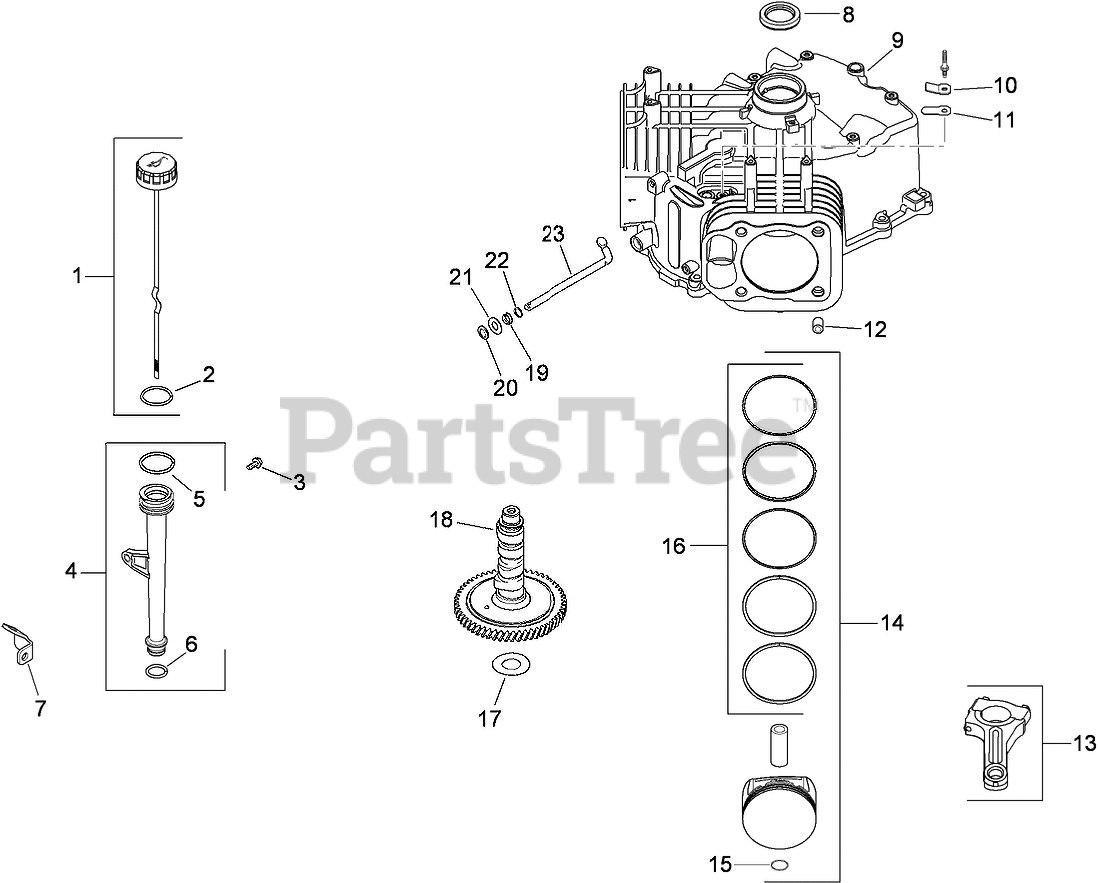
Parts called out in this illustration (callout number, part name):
1	Dipstick Asm (INCLUDES REF 2)
2	O-RING
3	SCREW-FLG, THD FRM (M5X0.8X13)
4	OIL FILL TUBE ASM (INCLUDES REF 5, 6)
5	O-RING (UPPER OIL FILL TUBE)
6	O-RING (LOWER OIL FILL TUBE)
7	BRACKET-TUBE, OIL FILL
8	SEAL-OIL (HELIX LIP)
9	SHORT BLOCK
10	RETAINER-REED, BREATHER
11	REED-BREATHER
12	PIN-LOCATING
13	ROD-CONNECTING (STD)
14	PISTON W/RING SET (STD) (INCLUDES REF 15, 16)
14	PISTON W/RING SET (.08) (INCLUDES REF 15, 16)
14	PISTON W/RING SET (.25) (INCLUDES REF 15, 16)
15	RETAINER-PIN, PISTON
16	PISTON RING SET (STD)
16	PISTON RING SET (.25)
17	SHIM-CAMSHAFT (WHITE .028)
17	SHIM-CAMSHAFT (BLUE .03)
17	SHIM-CAMSHAFT (RED .032)
17	SHIM-CAMSHAFT (YELLOW .034)
17	SHIM-CAMSHAFT (GREEN .036)
17	SHIM-CAMSHAFT (GRAY .038)
17	SHIM-CAMSHAFT (BLACK .04)
18	CAMSHAFT KIT
19	SEAL-CROSS SHAFT, GOVERNOR
20	RETAINER-RING
21	WASHER-FLAT (9MM)
22	WASHER-FLAT (11/32)
23	SHAFT-CROSS, GOVERNOR
